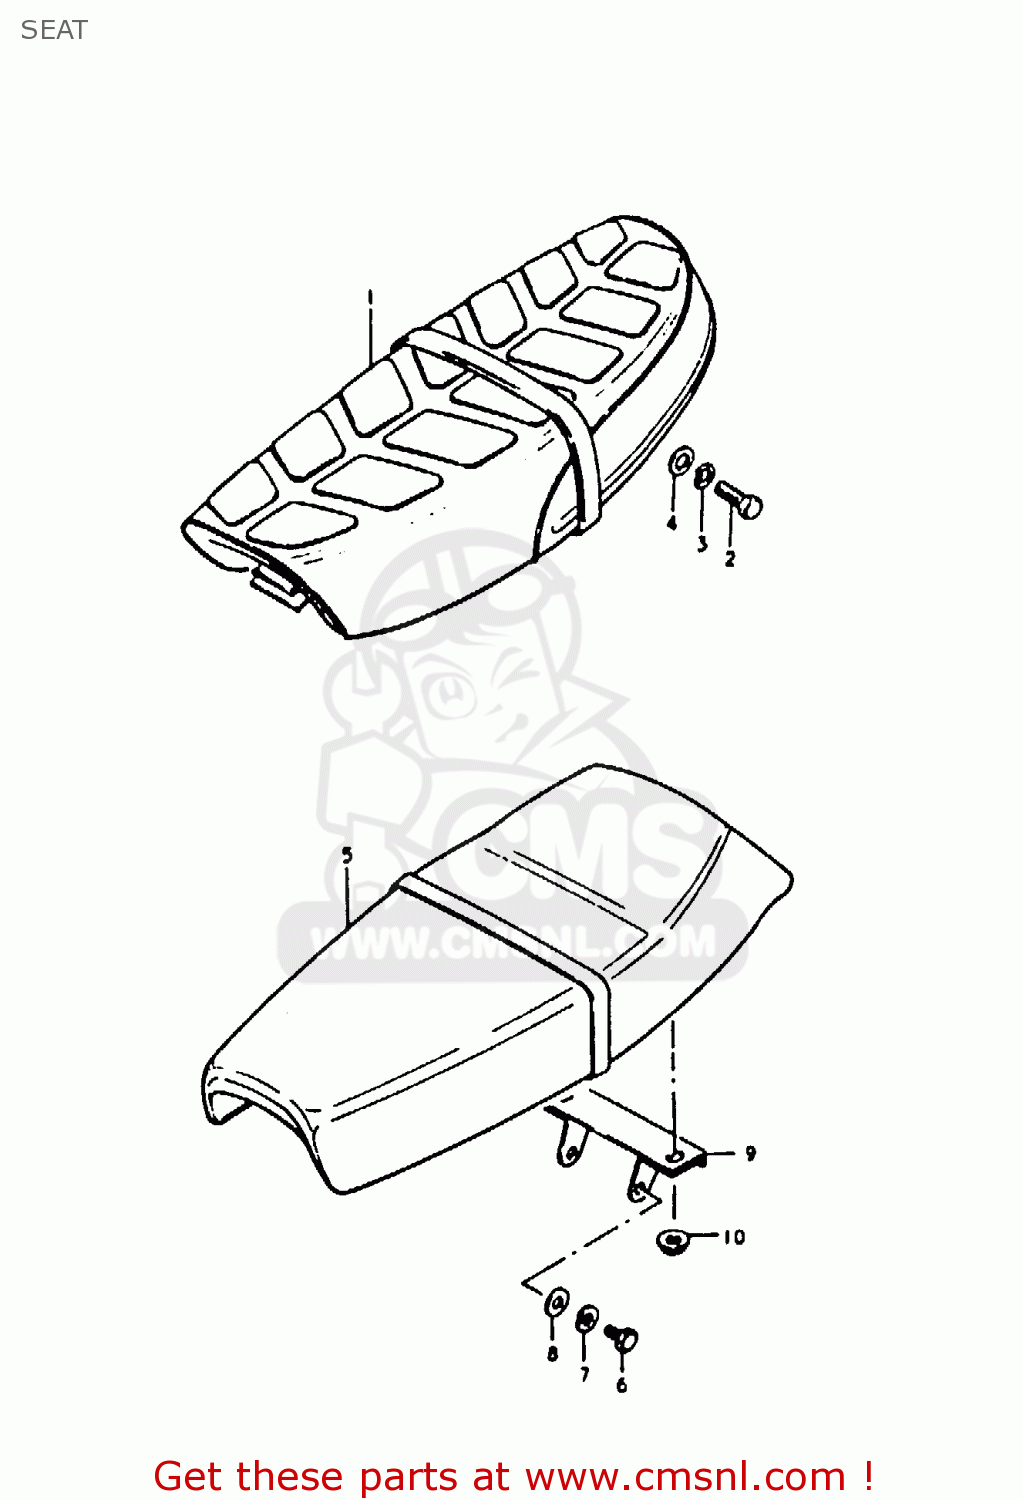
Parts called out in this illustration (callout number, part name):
5	SEAT
6	BOLT
7	LOCK WASHER
8	WASHER
9	PLATE,SEAT HOOK RR
10	NUT
